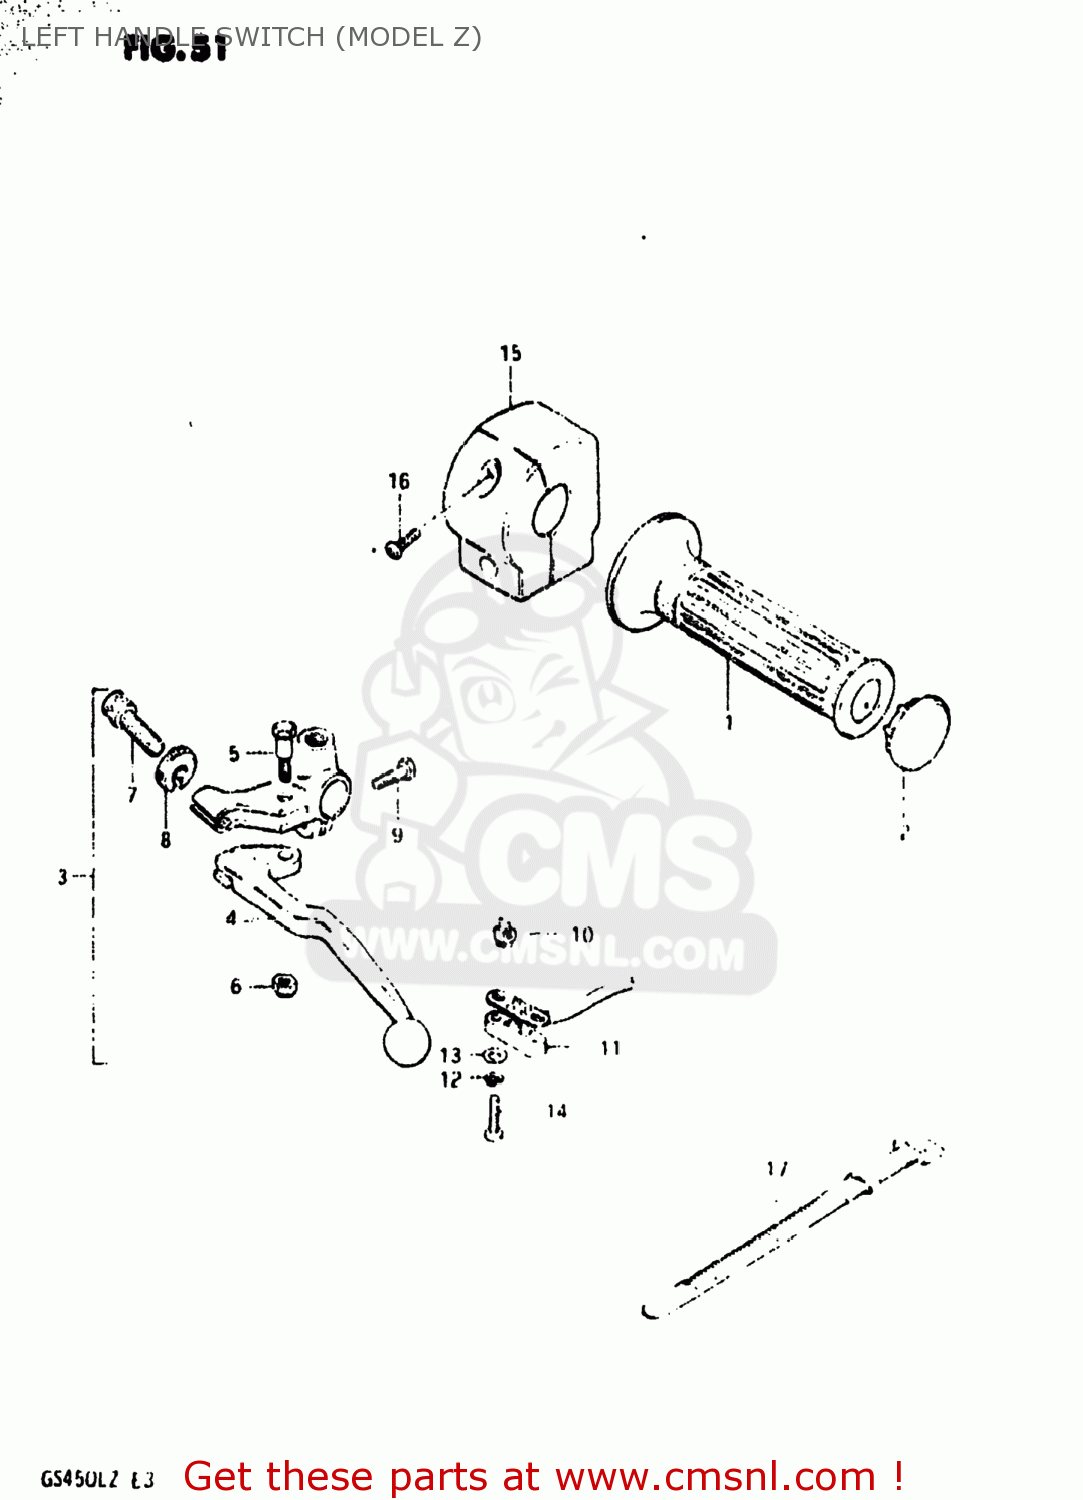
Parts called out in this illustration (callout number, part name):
1	GRIP,LEFT
2	CAP,GRIP END
3	LEVER ASSEMBLY
4	LEVER,CLUTCH
5	BOLT,LEVER
6	NUT 6MM
7	ADJUSTER,CABLE
8	NUT,CABLE ADJUSTER
9	BOLT,CLUTCH LEVER HOLDER
10	CONTACT,SWITCH
11	COVER,FR BK TERMINAL BASE
12	LOCK WASHER
13	WASHER
14	SCREW
15	SWITCH ASSEMBLY,HANDLE,LEFT
16	SCREW
17	CLAMP(L:120)
